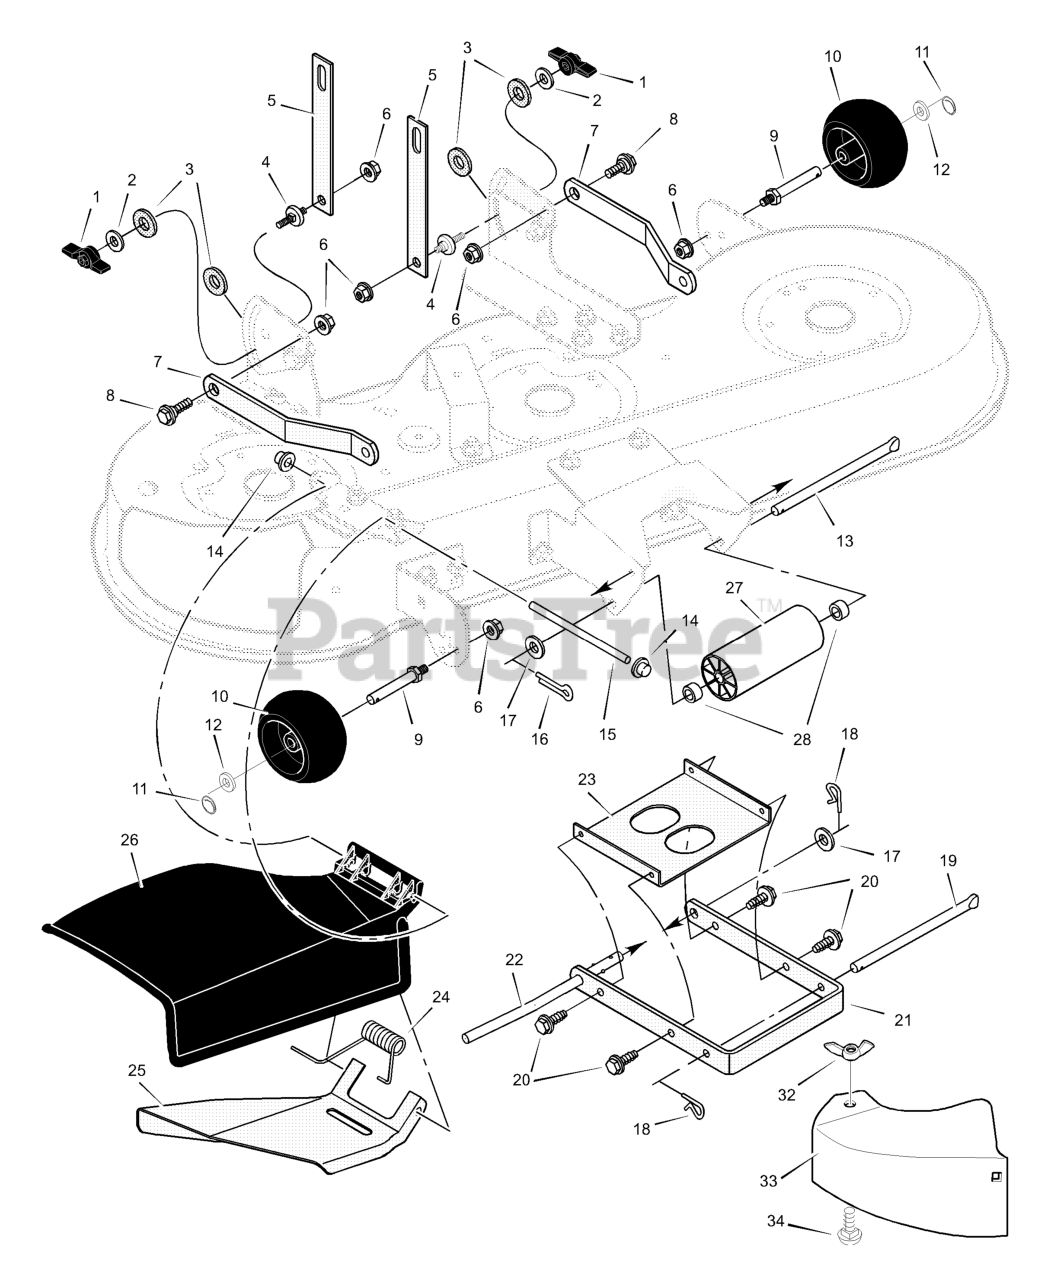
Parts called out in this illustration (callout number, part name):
1	Wingnut
3	Pad, Friction
4	Pin, Hanger
5	Link, Lift
6	Nut, Flange
7	Bracket, Suspension
8	Bolt, Shoulder
9	BOLT, Gauge Wheel
10	Wheel, Gage
11	Pin, Hair
13	Rod, Deck Suspension
14	Cap, Push
15	Rod, Pivot
16	Pin, Cotter
18	Pin, Hair
19	Rod, Hanger
21	Bracket, Front Suspension
22	Rod, Hanger
23	Stiffener
24	Spring, Torsion
25	Deflector, Inside
26	Deflector, Chute
32	Wingnut
33	Plate, Mulch
34	Bolt, Carriage
